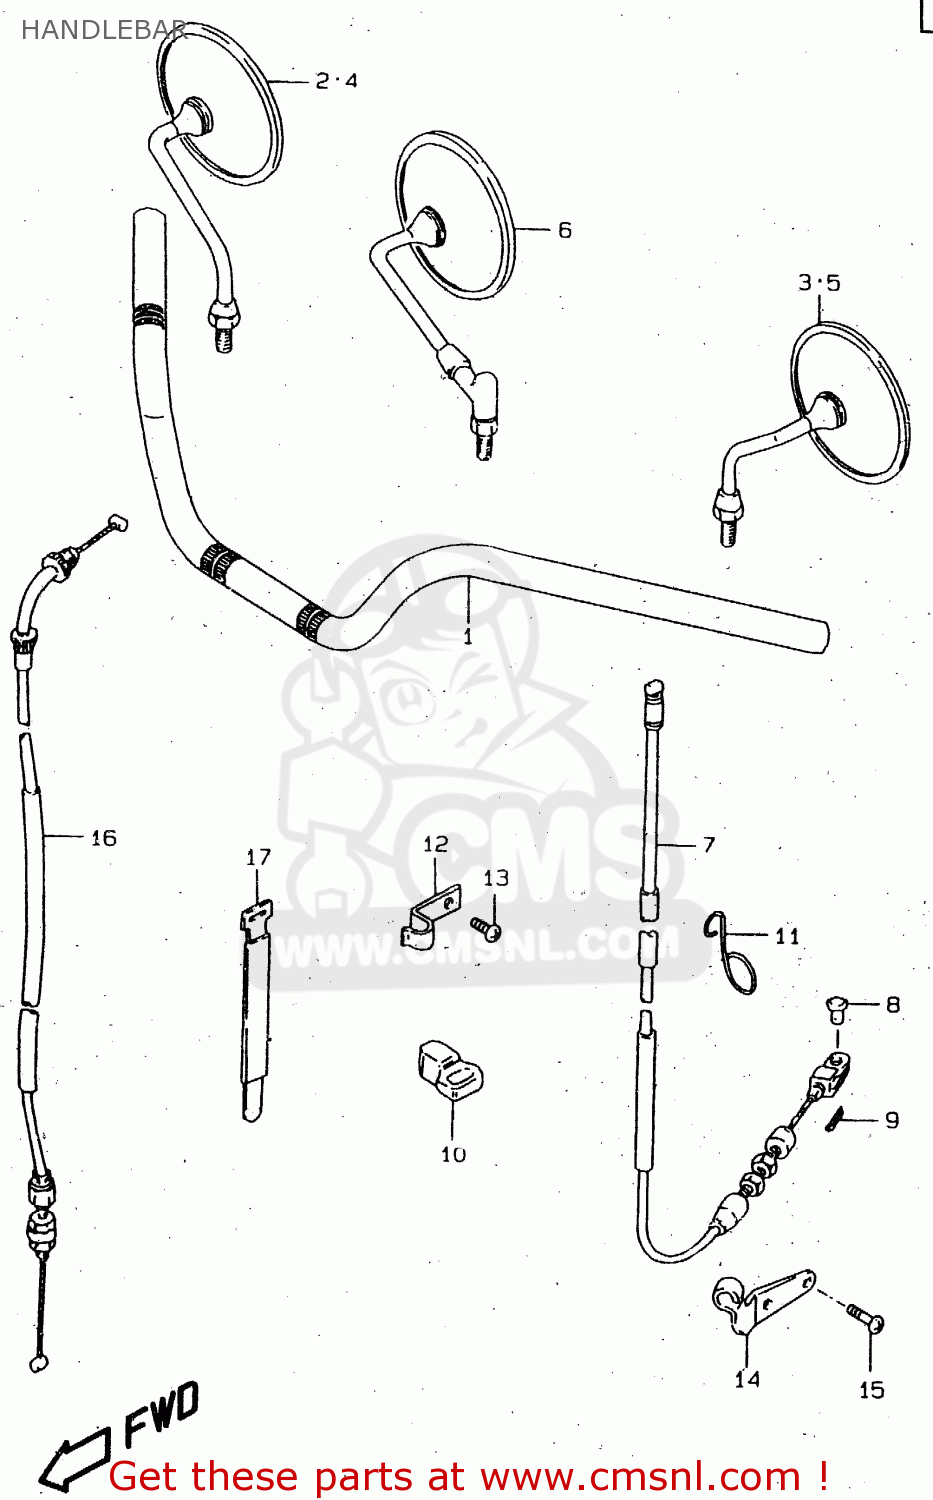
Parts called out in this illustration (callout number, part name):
1	HANDLEBAR
2	MIRROR ASSY,RH
3	MIRROR ASSY,LH
4	MIRROR, REAR VIEW RH
5	MIRROR, REAR VIEW LH
6	MIRROR ASSY,RH
7	CABLE ASSY,CLUTCH
8	PIN(L:13)
9	PIN
10	GUIDE,CLUTCH CABLE
11	GUIDE,CABLE
12	CLAMP,CLUTCH CABLE NO.1
13	SCREW
14	STOPPER,CLUTCH CABLE
15	SCREW
16	CABLE ASSY,THROTTLE
17	CLAMP(L:235)
